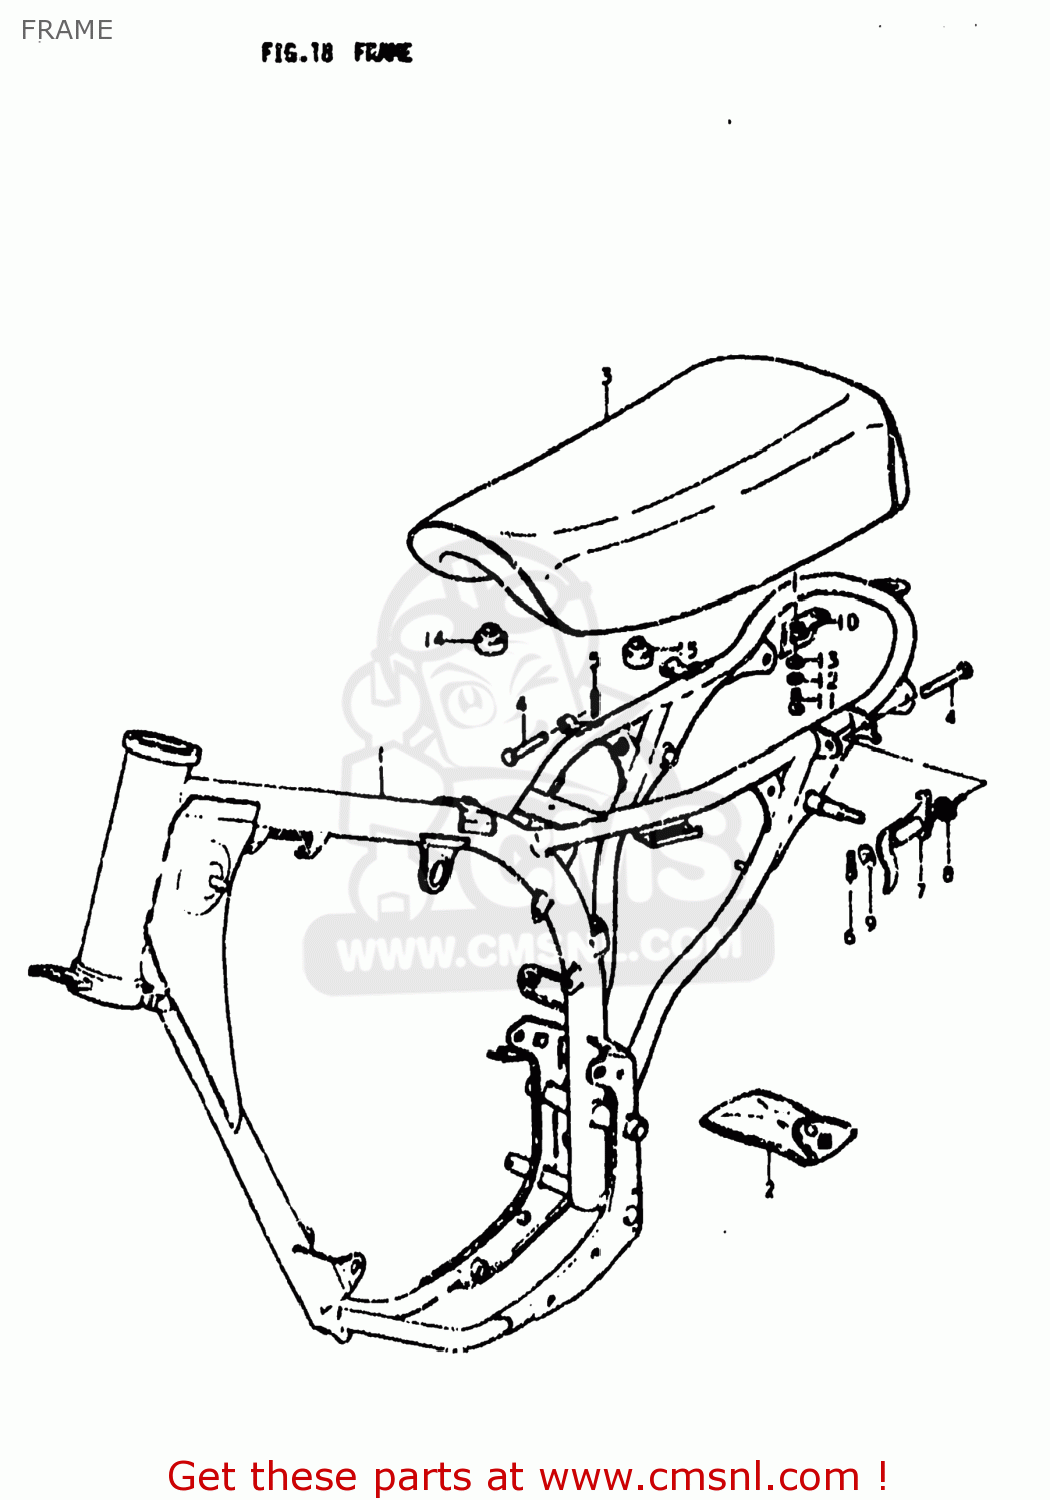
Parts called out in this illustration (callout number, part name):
1	FRAME
2	TOOL SET
3	SEAT ASSEMBLY
4	PIN
5	PIN
6	CLIP
7	STRIKER,SEAT LOCK
8	SPRING
9	WASHER
10	PLATE,SEAT CLAMP GUIDE
11	BOLT
12	LOCK WASHER
13	WASHER
14	CUSHION(11.5X22X20)
15	CUSHION
